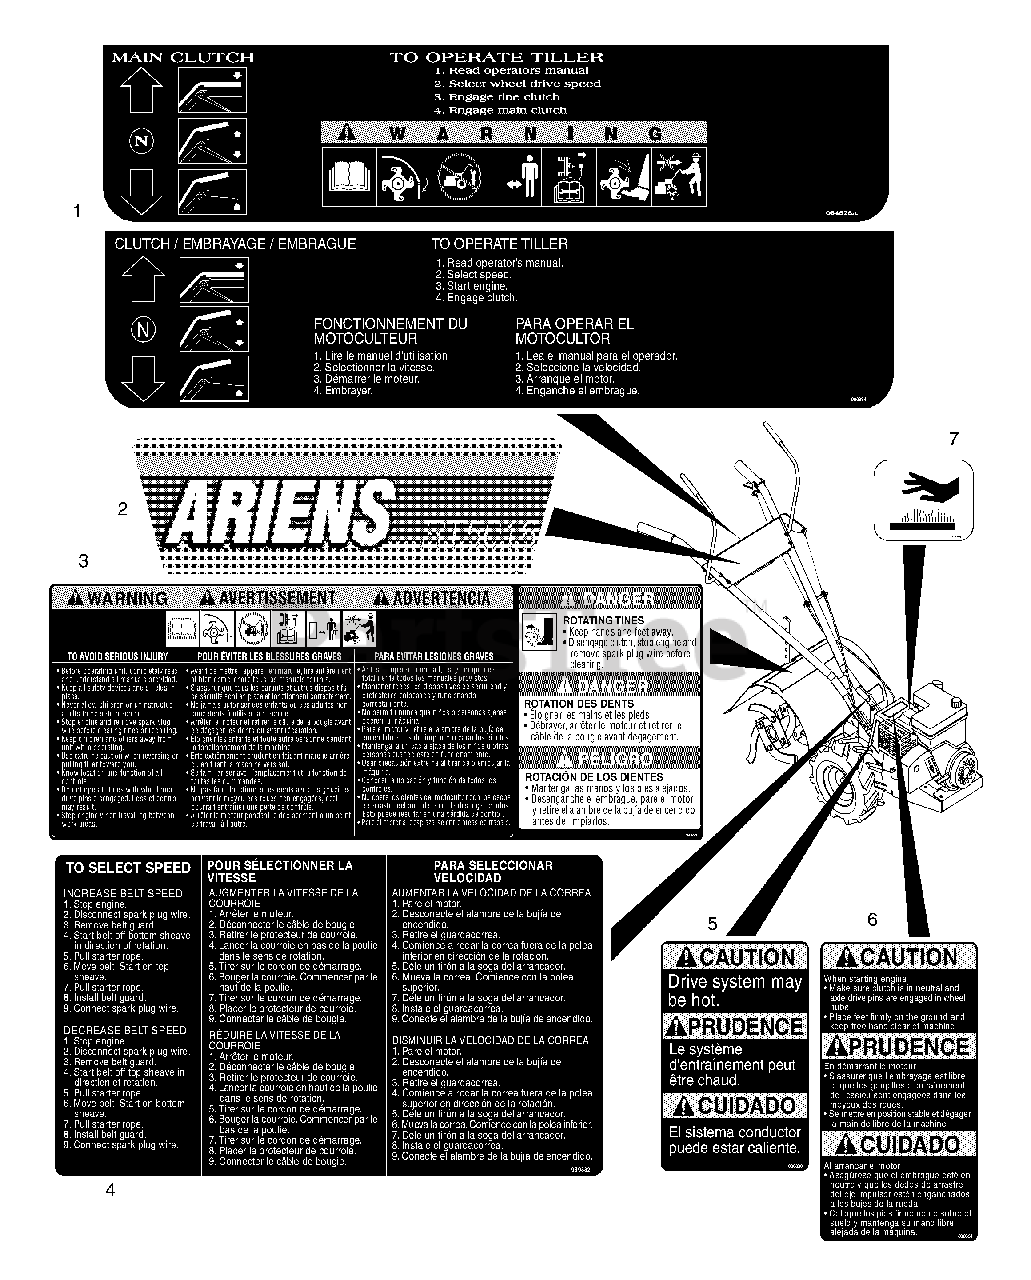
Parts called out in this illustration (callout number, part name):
1	DECAL, DASH CONTROL SER. 18"
2	DECAL, RT5018 DASH
3	DECAL, WARNING & DANGER
4	DECAL, SELECT SPEED
5	DECAL, CAUTION-HOT
6	DECAL, CAUTION-ENG. START
7	DECAL, HOT SURFACE
